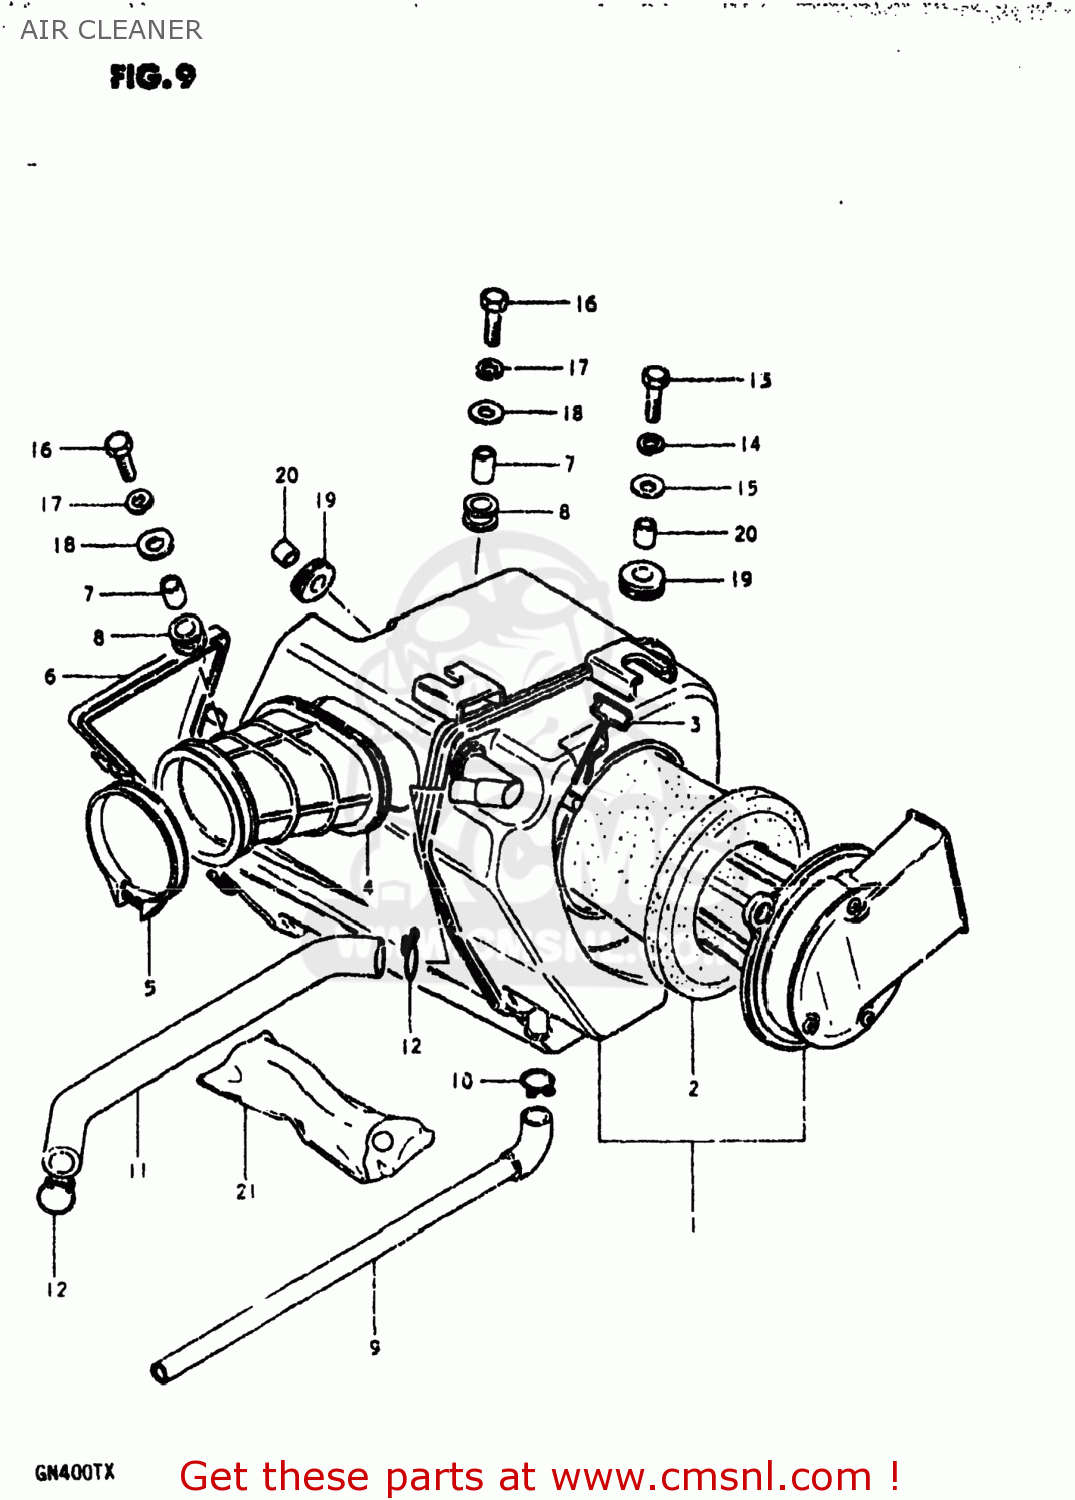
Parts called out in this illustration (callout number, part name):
1	CLEANER ASSEMBLY,AIR
2	FILTER ASSY
3	SNAP PIN,AIR CLEANER
4	TUBE,AIR CLEANER OUTLET
5	CLAMP
6	CAP,TOOL BOX
7	SPACER
8	CUSHION
9	DRAIN TUBE
10	CLIP
11	TUBE,BREATHER
12	CLIP
13	BOLT
14	LOCK WASHER
15	WASHER
16	BOLT
17	LOCK WASHER
18	WASHER
19	CUSHION
20	SPACER(6.5X10.5X6.5)
21	TOOL SET
